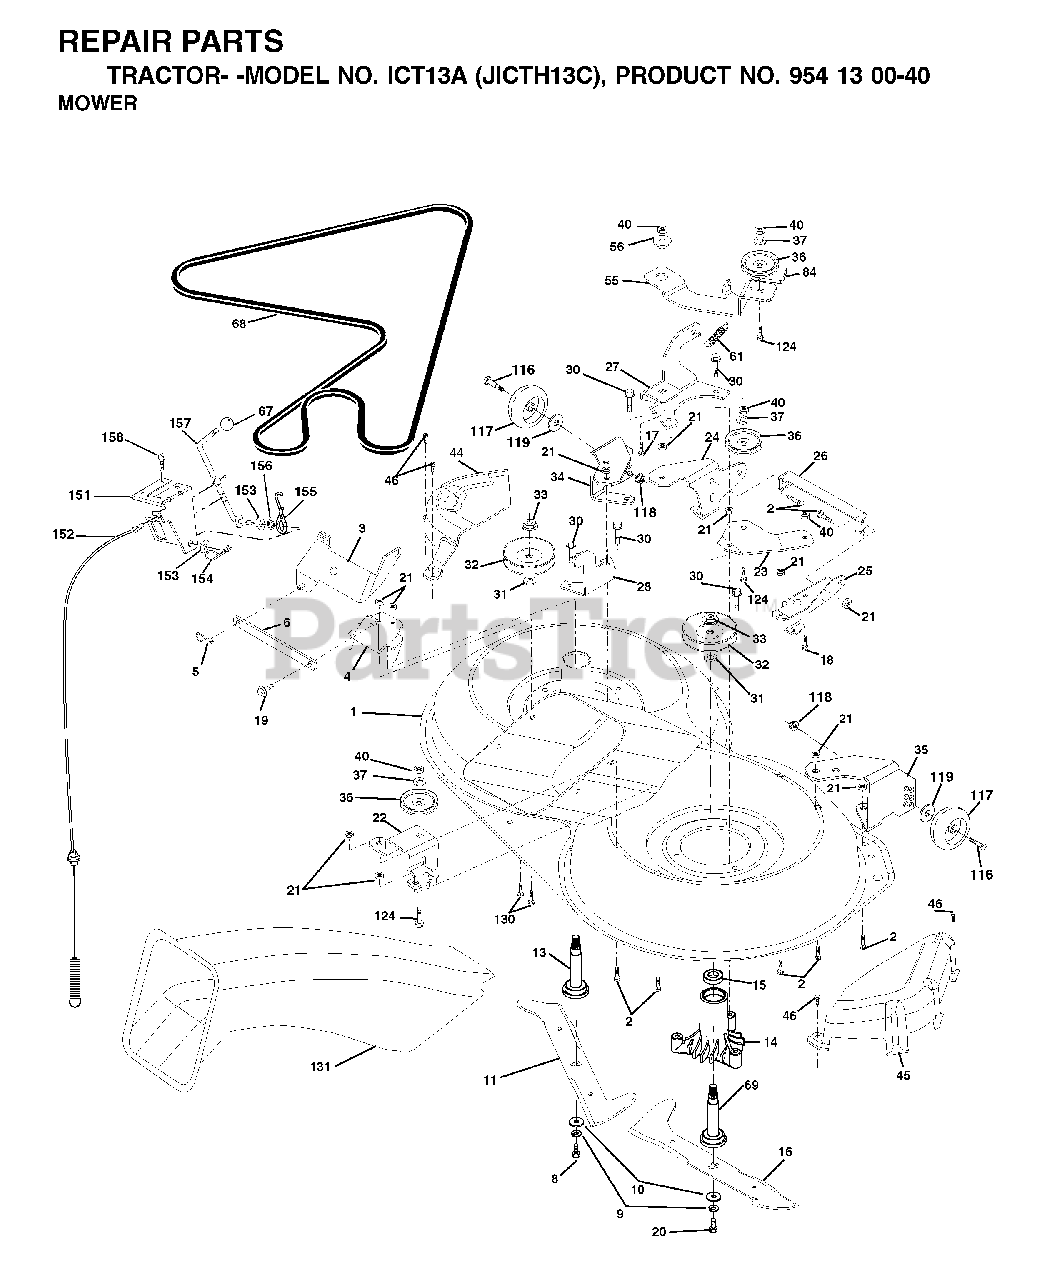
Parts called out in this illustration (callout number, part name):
1	MOWER HOUSING, DECK
2	BOLT
3	BRACKET
5	RETAINER-SPRNG RB
6	BAR SWAY
8	BLADE BOLT
9	LOCKWASHER
10	WASHER.BLADE
11	BLADE-LH 5PT STAR(CTH130)
12	BEARING
13	SHAFT ASM VENT
14	HSG MANDREL
16	BLADE RH 6PT STAR(CTH130)
17	BOLT.3/8-14X1.25
19	BOLT SHD 5/16-18
21	LOCKNUT
24	BRACKET
25	BRACKET
26	BRACE
28	BRACKET
30	SCREW THDROL ROLLING WASHER HD
31	WASHER
32	PULLEY, MANDREL
33	NUT
36	PULLEY.IDLER.4.25
40	LOCKNUT
45	COVER
46	SCREW.1/4-20X5/8
55	ARM IDLER
56	SPACER.RETAINER.MOWER
61	SPRING.TENSION.BELT
67	KNOB T (3/8 HOLE)
68	HEX-BELT 92 MOWER 105AA
69	SHAFT.ASM.W/LWR.BRG.RH.THREAD
84	KEEPER, BELT IDLER
116	BOLT, SHOULDER
117	WHEEL GAGE DONUT
118	LOCKNUT
119	WASHER
124	BOLT.3/8-16X1.50
128	WASHER FELT
131	CHUTE BAGGER
151	BRACKET, CLUTCH CABLE
153	WASHER FLAT 3/8"
154	SPRING RETAINER
155	SPRING RETENTION LEVER
156	SPACER CLUTCH CABLE
157	ROD CLUTCH CABLE 3/8"
158	SCREW LT
